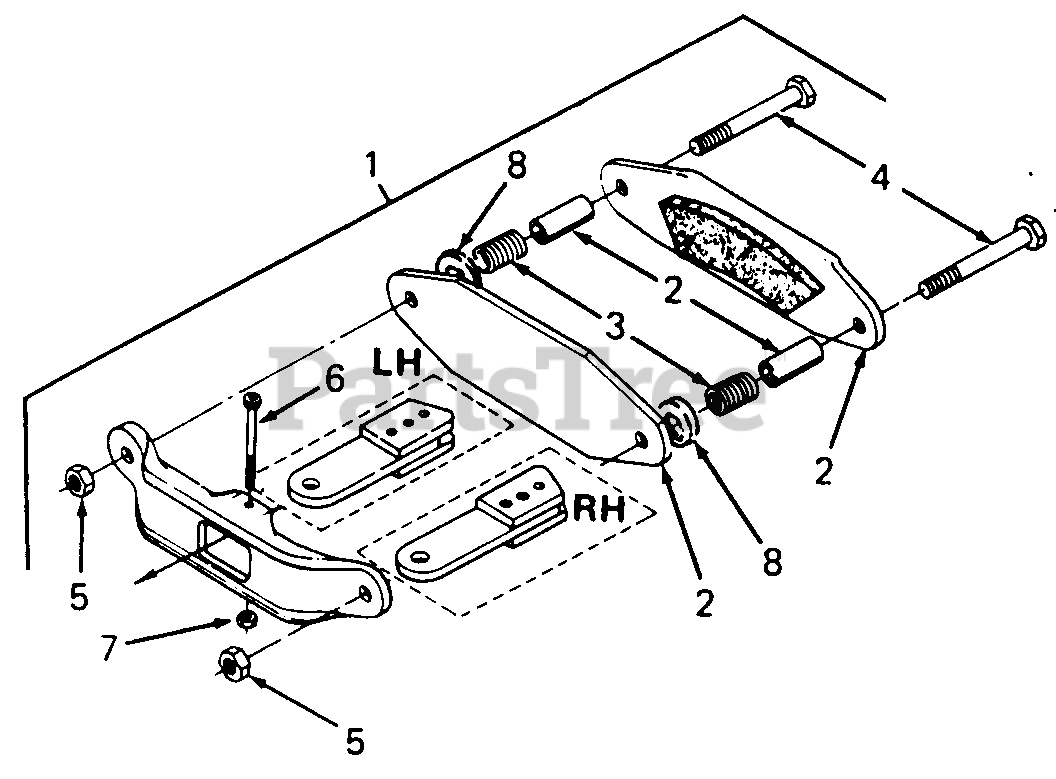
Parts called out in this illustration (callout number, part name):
1	Kit, Brake Caliper
2	Puck Kit, Brake
3	Spring, Compression
4	Screw, Hex Cap, 3/8-24 X 2.25 Lg
5	Nut, Hex Lock, 3/8-24 GR5
6	Screw, Socket Hd Shld, 1/4-20 X 1.25 Lg
7	Nut, Hex Top Lock Jam, 1/4-20 GR5
8	Washer, Flat, .390 X 1.0 X .030 Thk HDN
